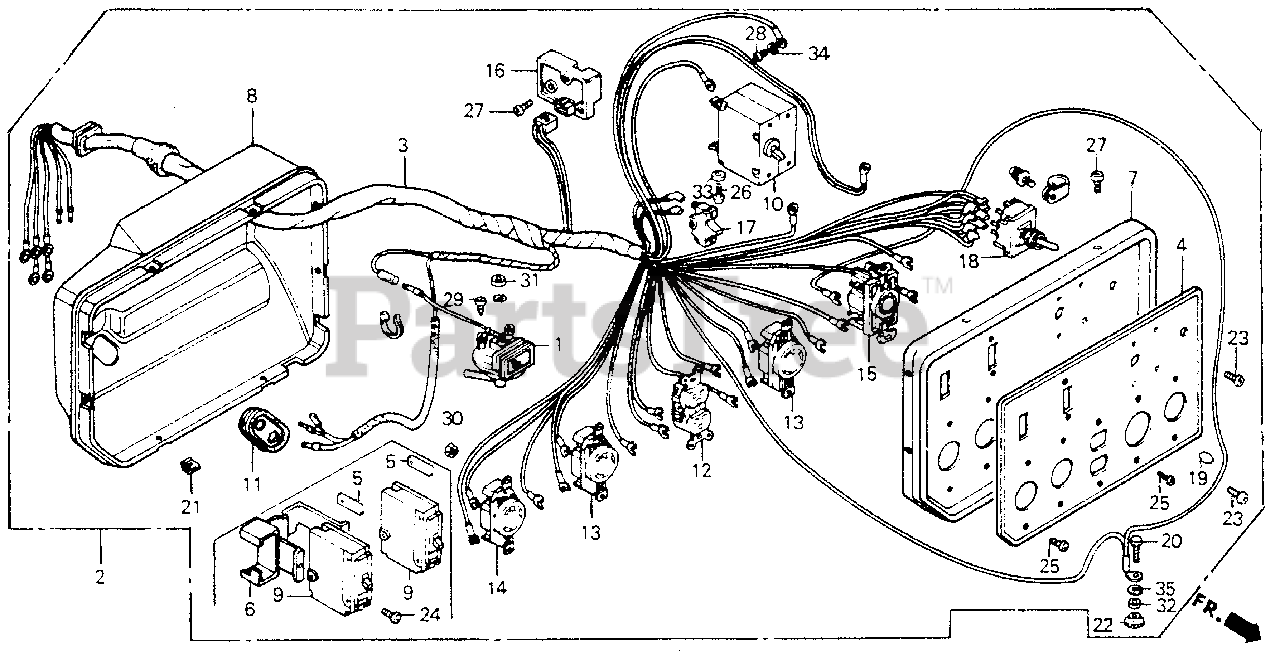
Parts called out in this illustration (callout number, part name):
1	SWITCH ASSY., UNIT
2	BOX ASSY., CONTROL *R8* (BRIGHT RED)
3	WIRE HARNESS ASSY. (NOT AVAILABLE)
4	MARK, SWITCH PANEL (NOT AVAILABLE)
5	TERMINAL, BREAKER
6	SUPPORT, BREAKER
7	PANEL, CONTROL *R8* (BRIGHT RED)
7	PANEL, CONTROL
8	CASE, CONTROL
9	BREAKER, CIRCUIT (17A)
10	BREAKER, CIRCUIT (17A) (NOT AVAILABLE)
11	GROMMET, UNIT SWITCH
12	RECEPTACLE ASSY. (125V-20A)
12	RECEPTACLE (20A/125V)
13	RECEPTACLE (20A-125V)
14	RECEPTACLE (3-PRONG) (30A/125V)
15	RECEPTACLE (20A/125-250V)
16	CONTROL UNIT, IDLE
17	SWITCH ASSY., IDLE CONTROL (NOT AVAILABLE)
18	SWITCH ASSY., VOLT CHANGE
19	MARK, GROUND
20	BOLT, HEX. (6X18)
21	NUT, SPRING (5MM)
22	NUT, SPECIAL (6MM)
23	SCREW, PAN (3X6)
24	SCREW, PAN (4X6)
25	SCREW, PAN (4X8)
26	SCREW, PAN (4X10)
27	SCREW, PAN (5X12)
28	SCREW, PAN (5X12)
29	SCREW, TAPPING (5X10)
30	NUT, HEX. (4MM)
31	NUT, HEX. (5MM)
32	NUT, HEX. (6MM)
33	WASHER, SPRING (4MM)
34	WASHER, SPRING (5MM)
35	WASHER, SPRING (6MM)
